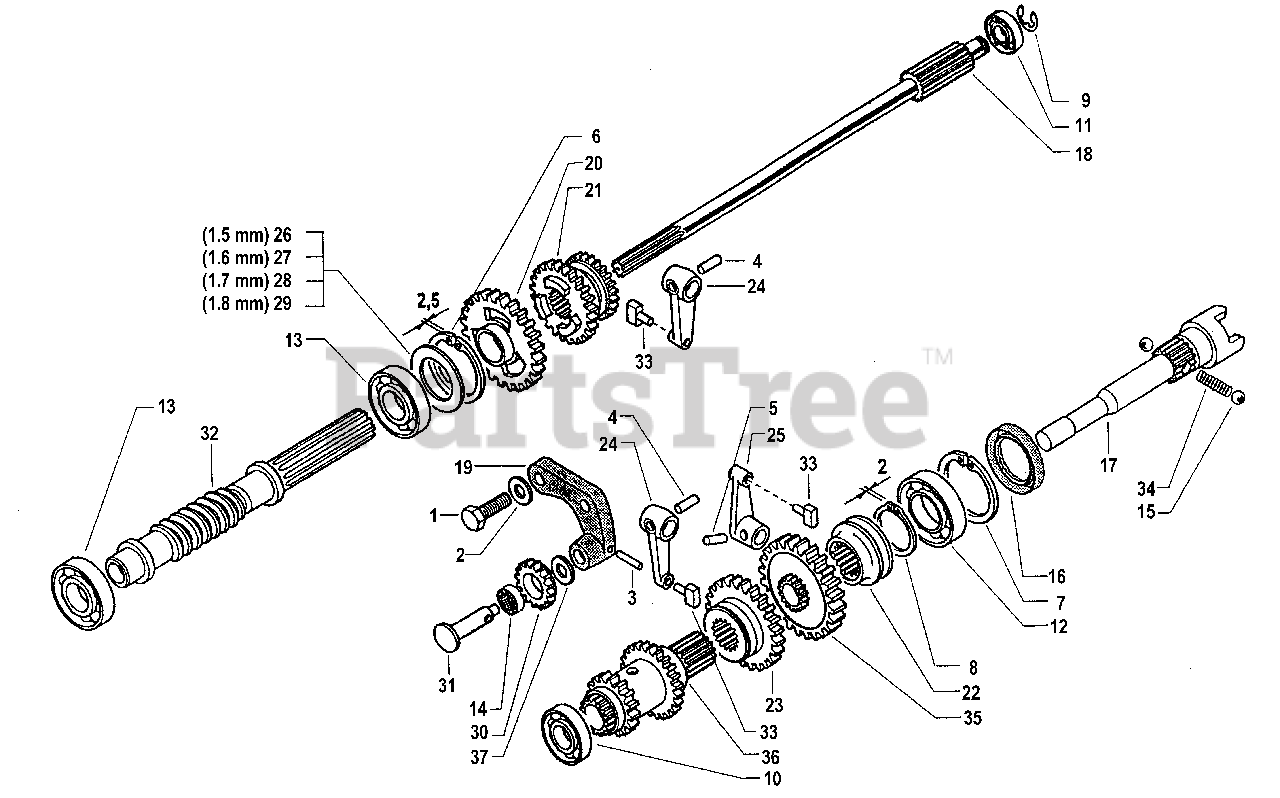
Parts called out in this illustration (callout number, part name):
1	SCREW M10X30
2	SUPER WASHER 10
3	LOCKING PIN, 4X24 SPIRAL
4	LOCKING PIN, 6X24 SPIRAL
5	LOCKING PIN, 6X20 SPIRAL
6	CIRCLIP, INTERNAL
7	CIRCLIP, INTERNAL
8	CIRCLIP,EXTERNAL
9	RETAININGRING
10	BEARING,15X35X11
11	BEARING,15X42X13
12	BEARING,30X55X13
13	BEARING,25X52X15
14	BEARING,12X15X10
16	OIL SEAL, 38X55X7
18	MAIN DRIVE SHAFT
19	REVERSER BRACKET
21	DOUBLE SLIDER
23	SLIDER, REVERSER
24	LEVER, REVERSER
25	LEVER, PTO ENGAGMENT
26	SHIM, 1.5MM
27	SHIM, 1.6MM
30	REVERSE GEAR
31	PIN, REVERSE GEAR
34	SPRING, PTO BALLS
36	SECOND GEAR
